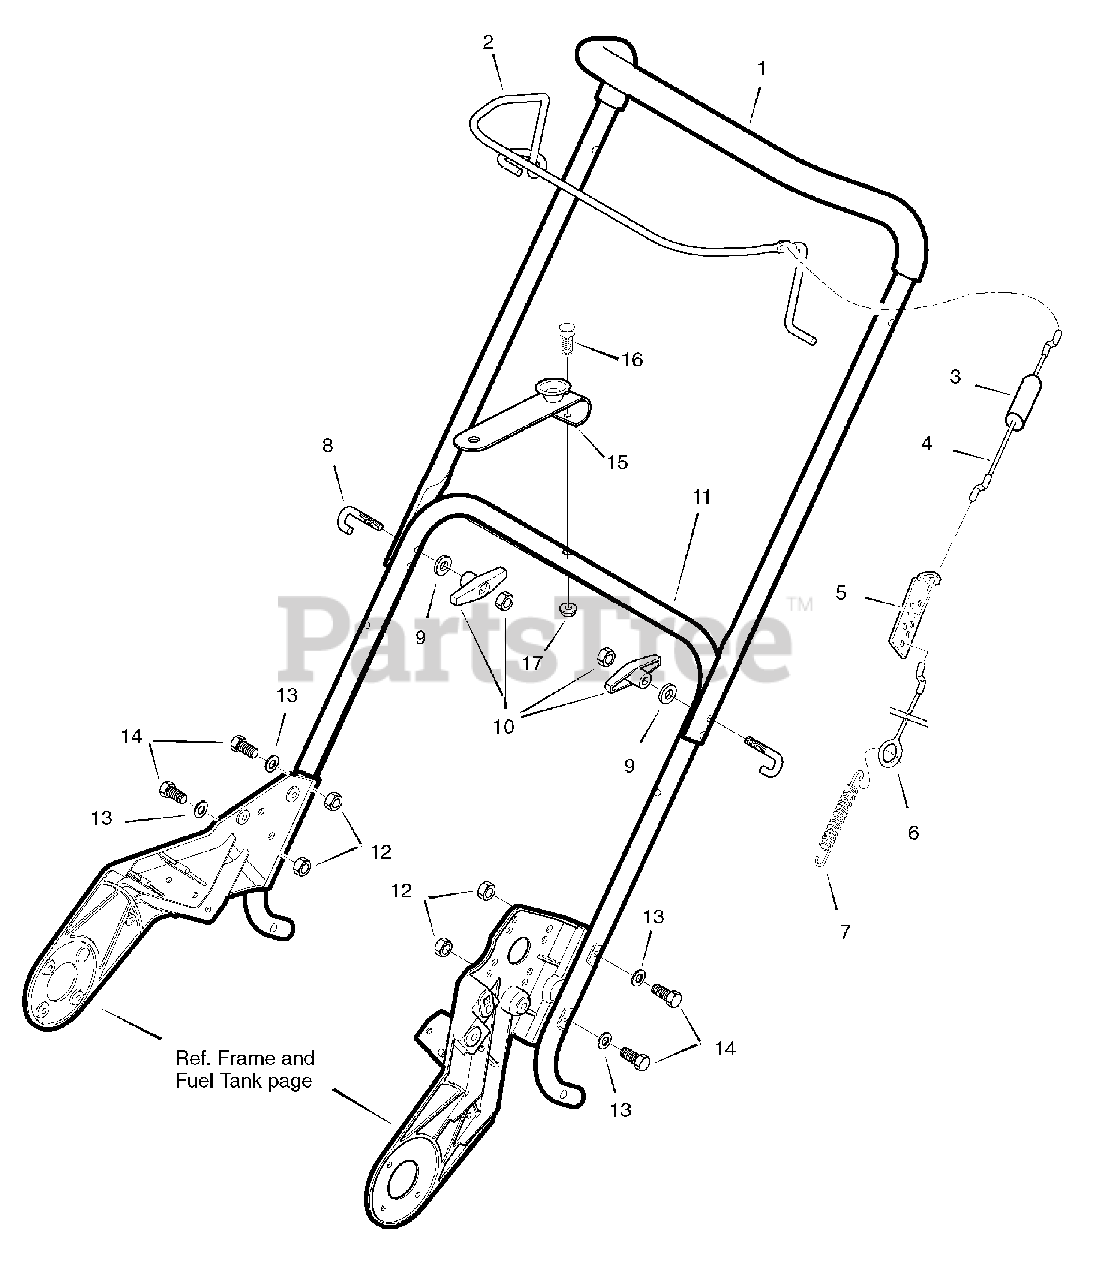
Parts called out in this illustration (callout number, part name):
1	HANDLE & GRIP ASSEMBLY
2	CONTROL, Bail
3	BOOT, Clutch Spring
4	CABLE, Upper Control
5	BRACKET, Control Adjust
6	CABLE, Lower Control
7	SPRING
8	Bolt, "U"
9	WASHER
10	KNOB, "T"
11	HANDLE, Lower
12	NUT
13	WASHER
14	SCREW, 1/4 - 20 x 1-1/4
15	BRACKET & CUP ASMY-CHUTE -BLACK
16	BOLT, Hex-Head, 1/4-20 X 1.50
17	NUT, Hex-Head, Nylock, 1/4-20
